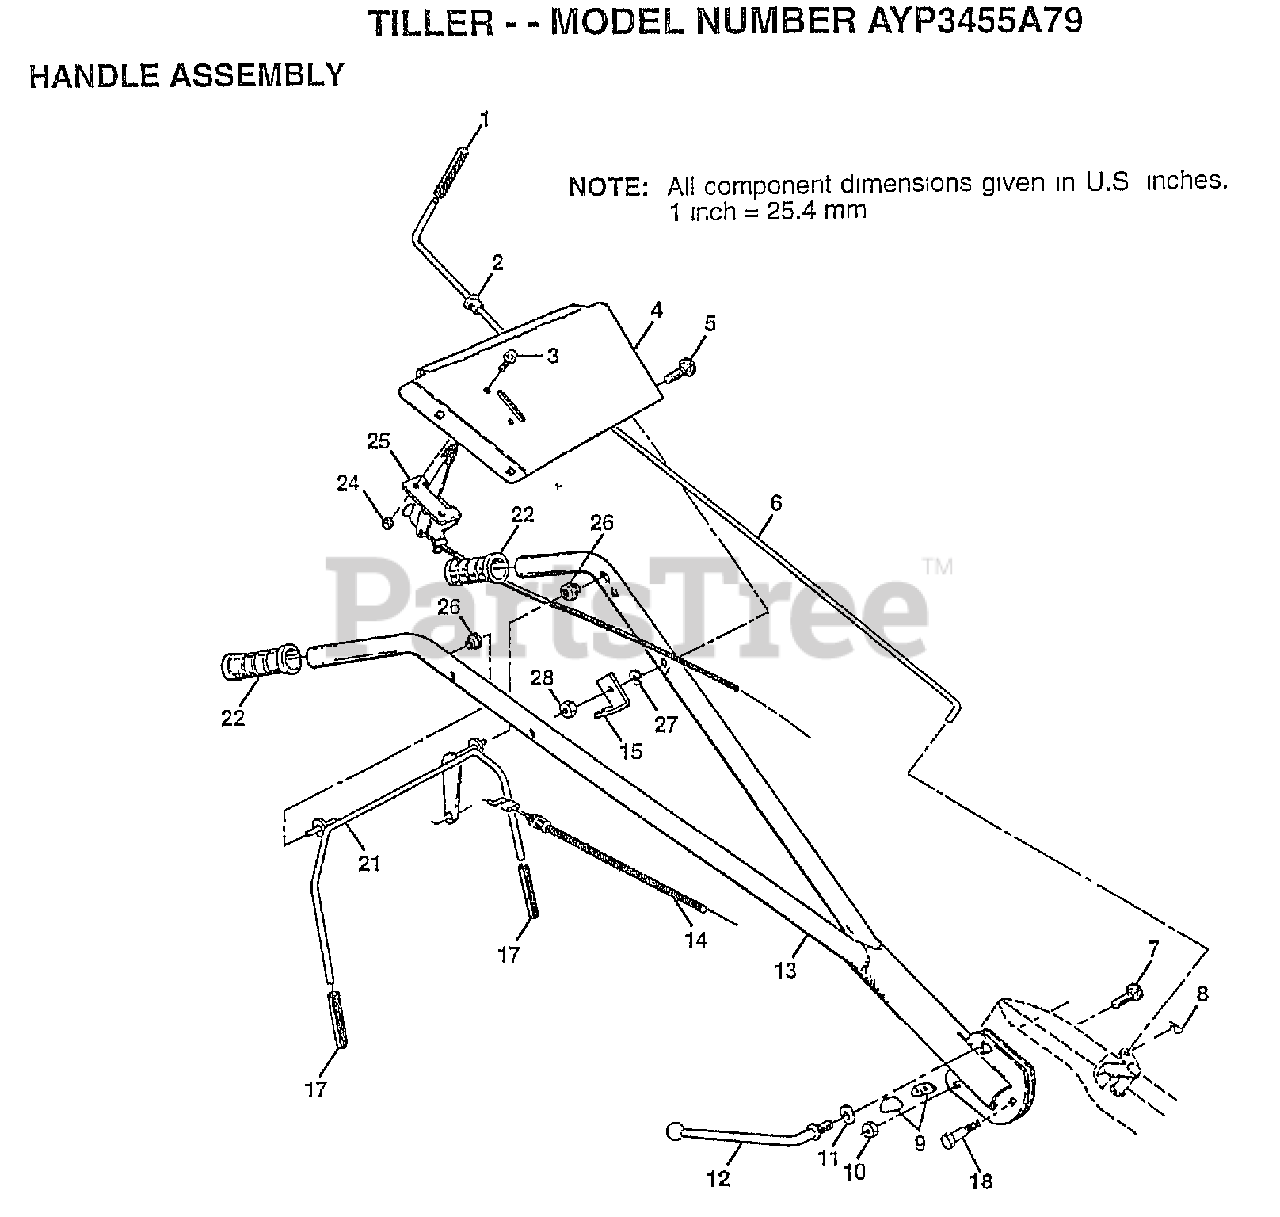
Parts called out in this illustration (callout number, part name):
1	GRIP TI
2	BUSHING
3	SCREW.PNHD.10-24
4	HANDLE BRACKET
5	BOLT CARRIAGE CRT
6	ROD SHIFT CRT
7	BOLT D
8	RETAINER M
9	LOCK CRT
10	LOCKNUT
11	WASHER CRT
12	LEVER LOCK CRT
14	CABLE.CLUTCH.Z-BE
15	BRACKET.CLUTCH.CA
17	GRIP BAR CRT
18	BOLT PIVOT
21	BAR.ASM.CNTRL.VPL
22	"GRIP,HANDLE"
25	"CONT,THROTTLE"
26	GROMMET.HANDLE.V-
27	LOCKWASHER
28	NUT
